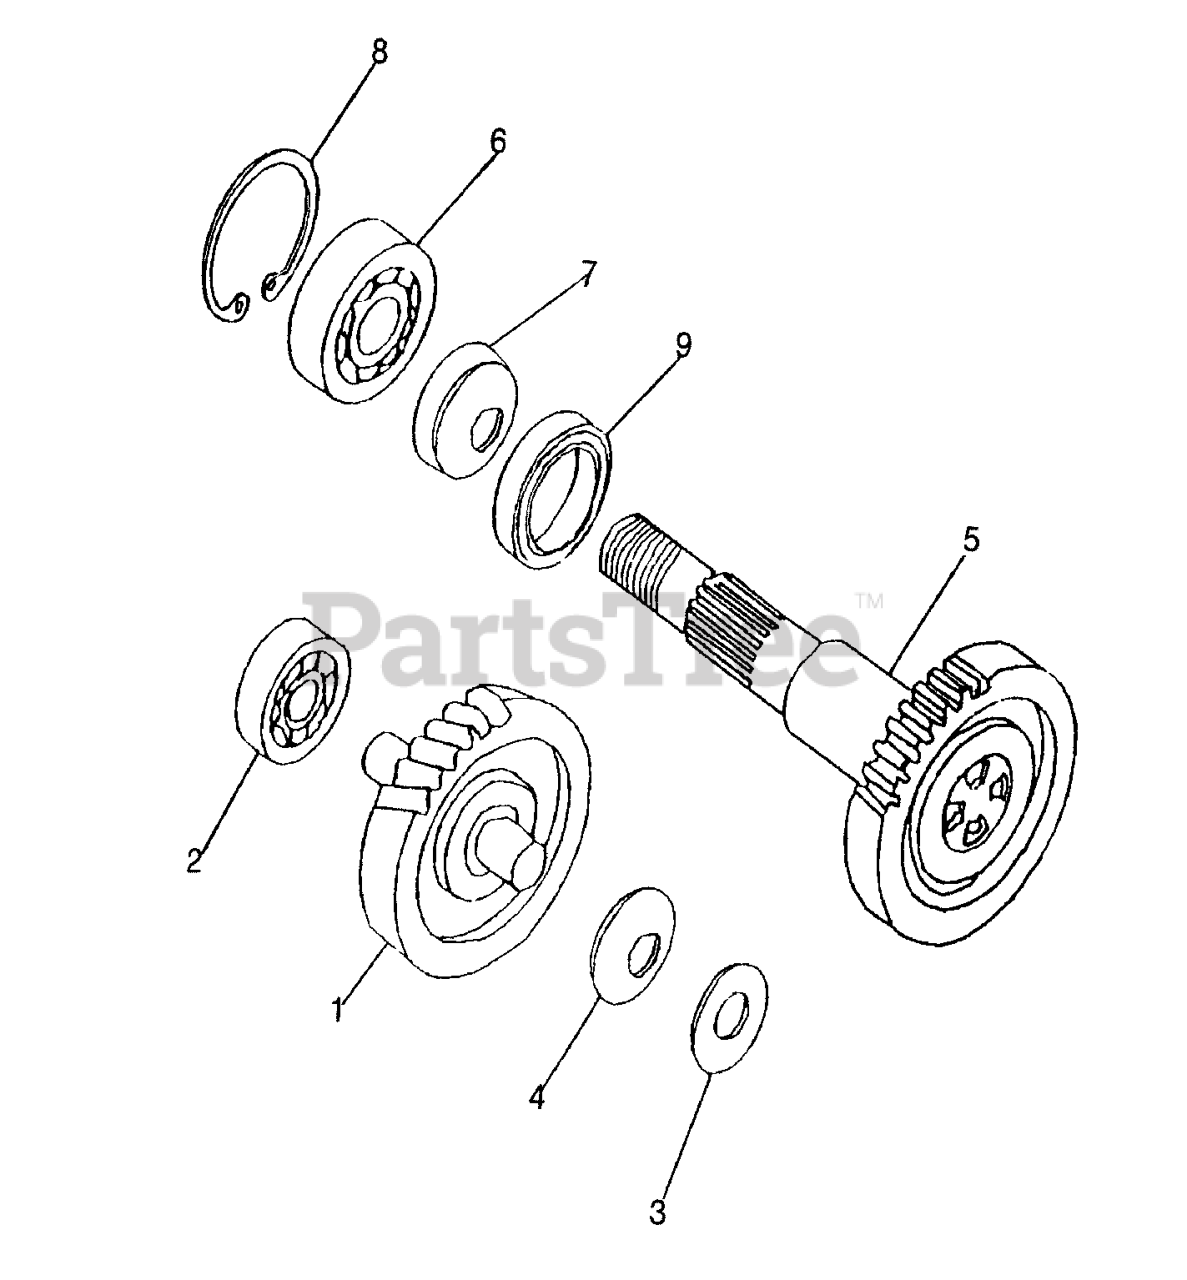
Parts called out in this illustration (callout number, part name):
1	SHAFT, IDLE
2	BEARING 6201
3	PLATE WASHER 12
4	WASHER, CONICAL
5	SHAFT, REAR BOX
6	NEEDLE BEARING
7	OIL SEAL
8	CIRCLIP
9	NEEDLE BEARING
